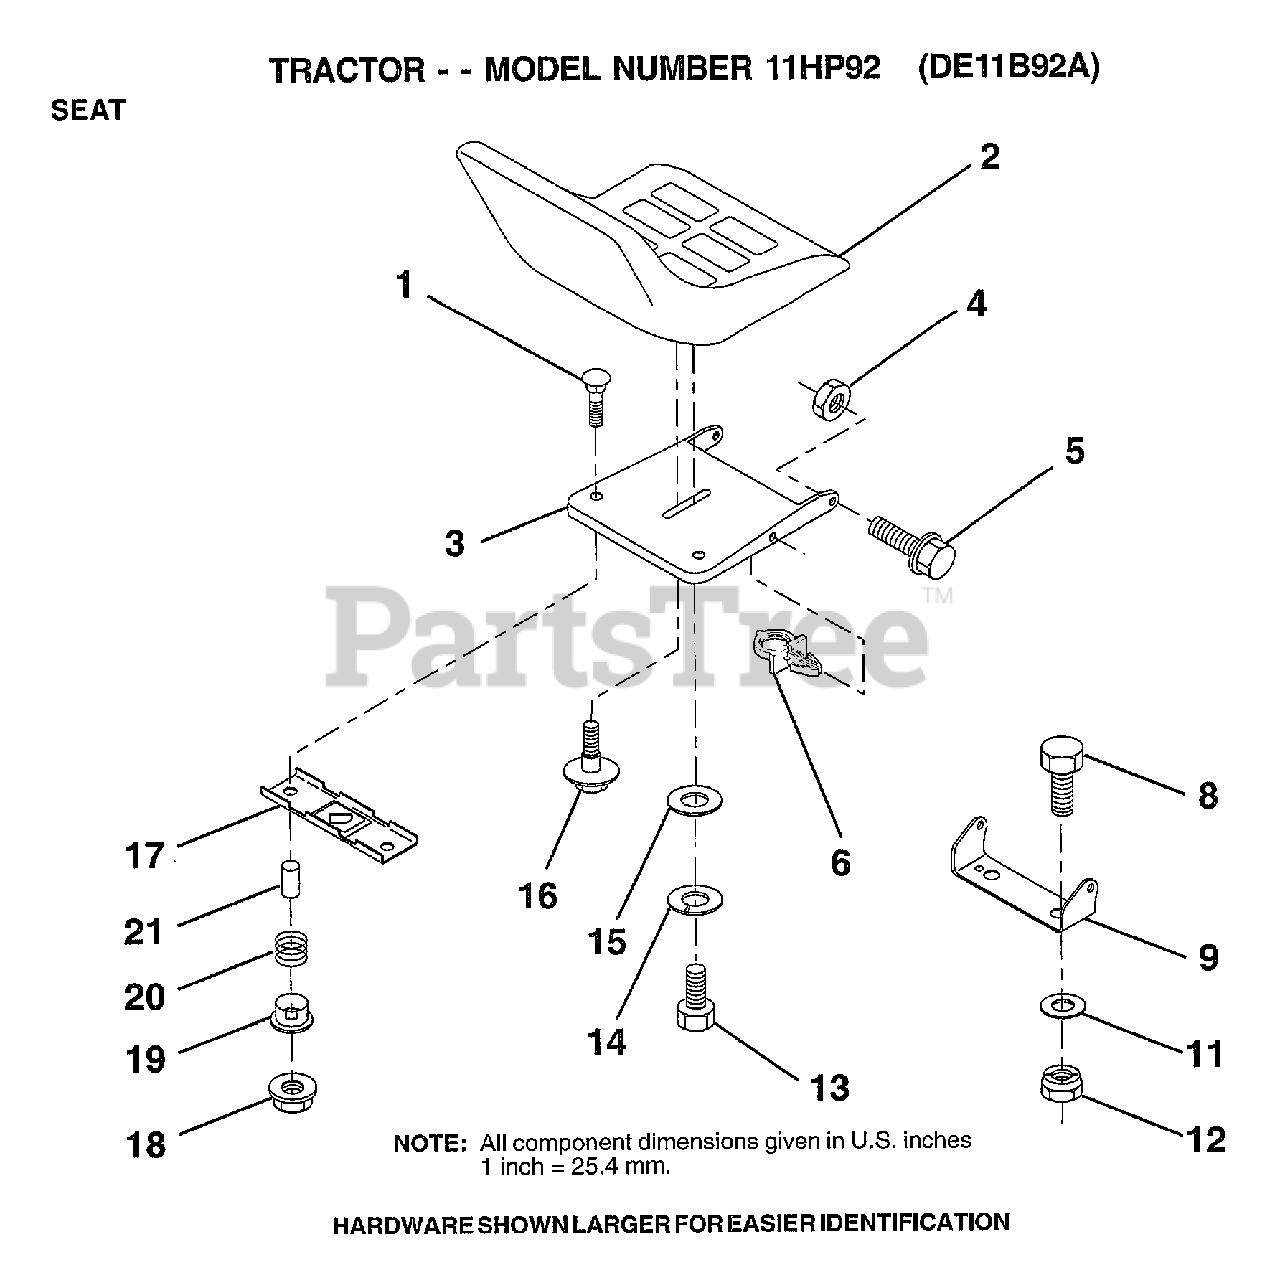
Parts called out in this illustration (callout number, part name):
1	BOLT-RD HD SQ NK
3	PAN-SEAT
4	NUT
5	BOLT
6	CLIP.PUSH-IN.HING
8	BOLT
9	BRACKET PVT SEAT
11	WASHER
12	NUT
13	BOLT HEX BLACK
14	LOCKWASHER
15	WASHER
16	"BOLT,SHOULDER"
17	BRKT SWITCH
19	BUSHING
20	SPRING
21	SPLIT SPACER
